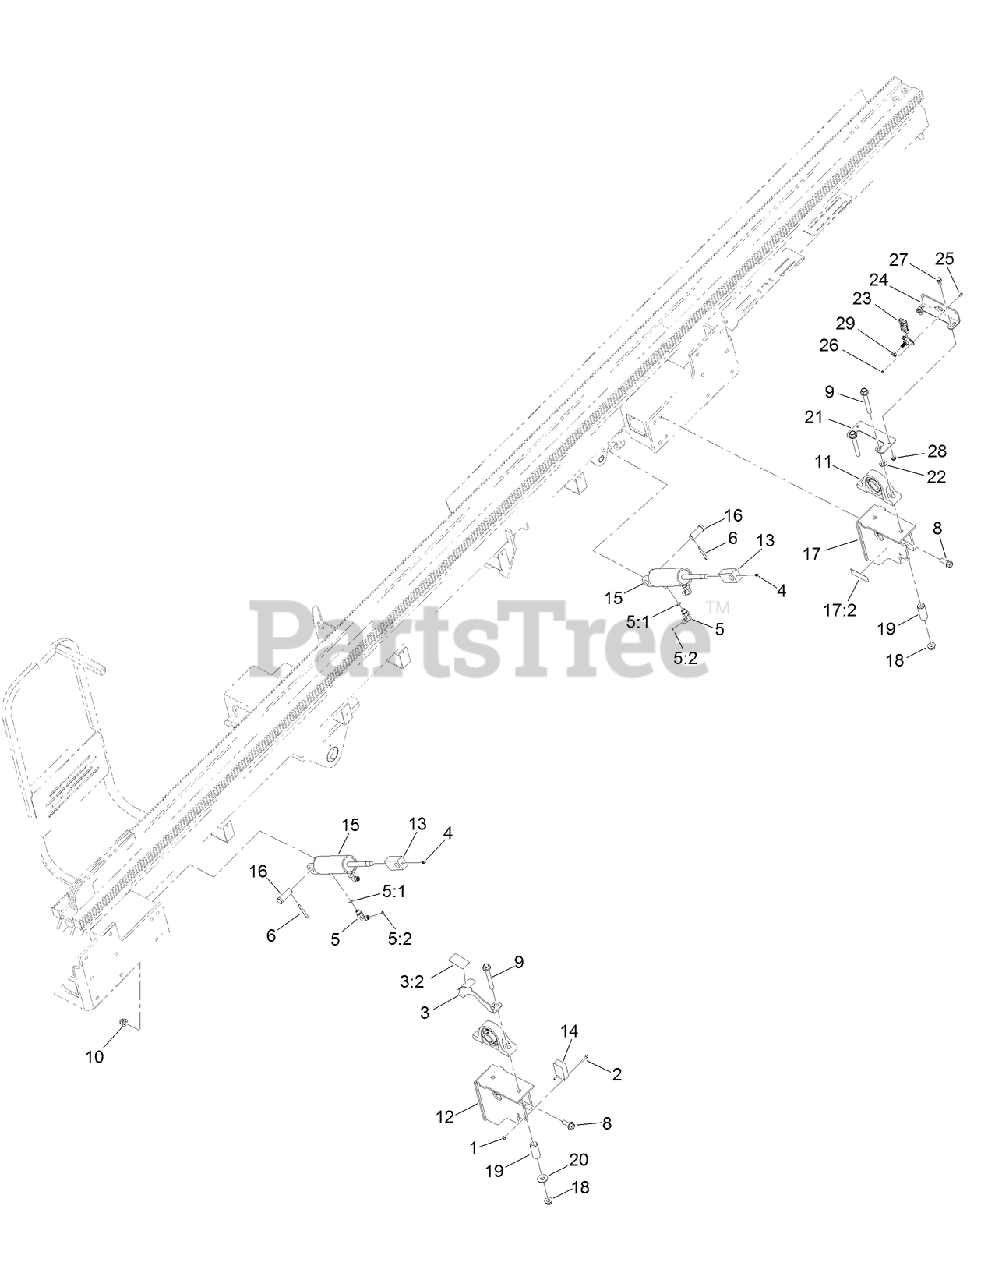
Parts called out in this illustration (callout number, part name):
1	NUT-HF
2	SCREW-HSH
3	ROW INDICATOR ASM
3:2	DECAL-ROW SELECTOR
4	FITTING-GREASE
5	FITTING-ELBOW 90
5:1	O-RING
5:2	O-RING
6	PIN-COTTER
8	SCREW-HFH
9	SCREW-HHF
10	NUT-HHF, LOCK
11	BEARING-PILLOW
12	MOUNT-BEARING
13	EYE-ROD, CYLINDER
14	SWITCH-PROXIMITY
15	HYD CYLINDER ASM
16	PIN-CLEVIS
17	BEARING MOUNT ASM
17:2	DECAL-ROYALTY
18	NUT-HEX FLANGE
19	SPACER
20	WASHER-FLAT
22	WASHER-FLAT
23	SENSOR-ROTARY
24	BRACKET-SENSOR, ROTARY
25	SCREW-HH
26	NUT-HHF
27	SCREW-HHF
28	NUT-LOCK, HHF
29	NUT-HEX
